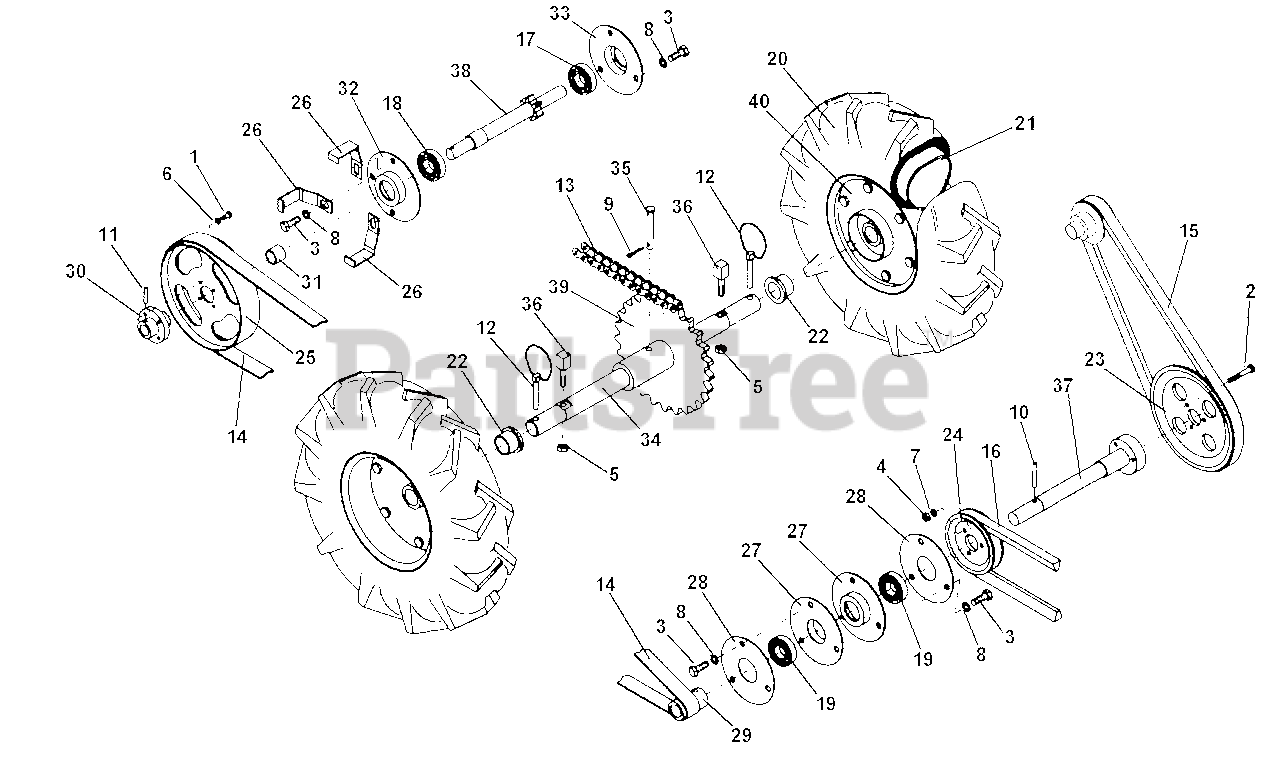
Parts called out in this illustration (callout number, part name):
1	SCREW M5X16
2	SCREW M6X40
3	SCREW M8X20
4	NUT, SELF LOCKING M6
5	NUT, SELF LOCKING M8
6	WASHER, FLAT M5.3
7	WAHSER, FLAT M6.3
8	WASHER M8.3
10	LOCKING PIN M6X25
11	LOCKING PIN M6X30
14	BELT, WHEEL DRIVE
15	BELT, CUTTERBAR
16	BELT, ENGINE
17	BEARING M15X35X11
18	BEARING M17X40X12
19	BEARING M20X42X12
20	TIRE 3.50X6
21	TUBE 3.50X6
27	BEARING SUPPORT HALF
28	BEARING SUPPORT HALF
29	ROLLER PULLEY
32	BEARING SUPPORT
33	BEARING SUPPORT
37	PULLEY SHAFT
38	PULLEY AND CHAIN SHAFT
39	CHAIN SPROCKET
